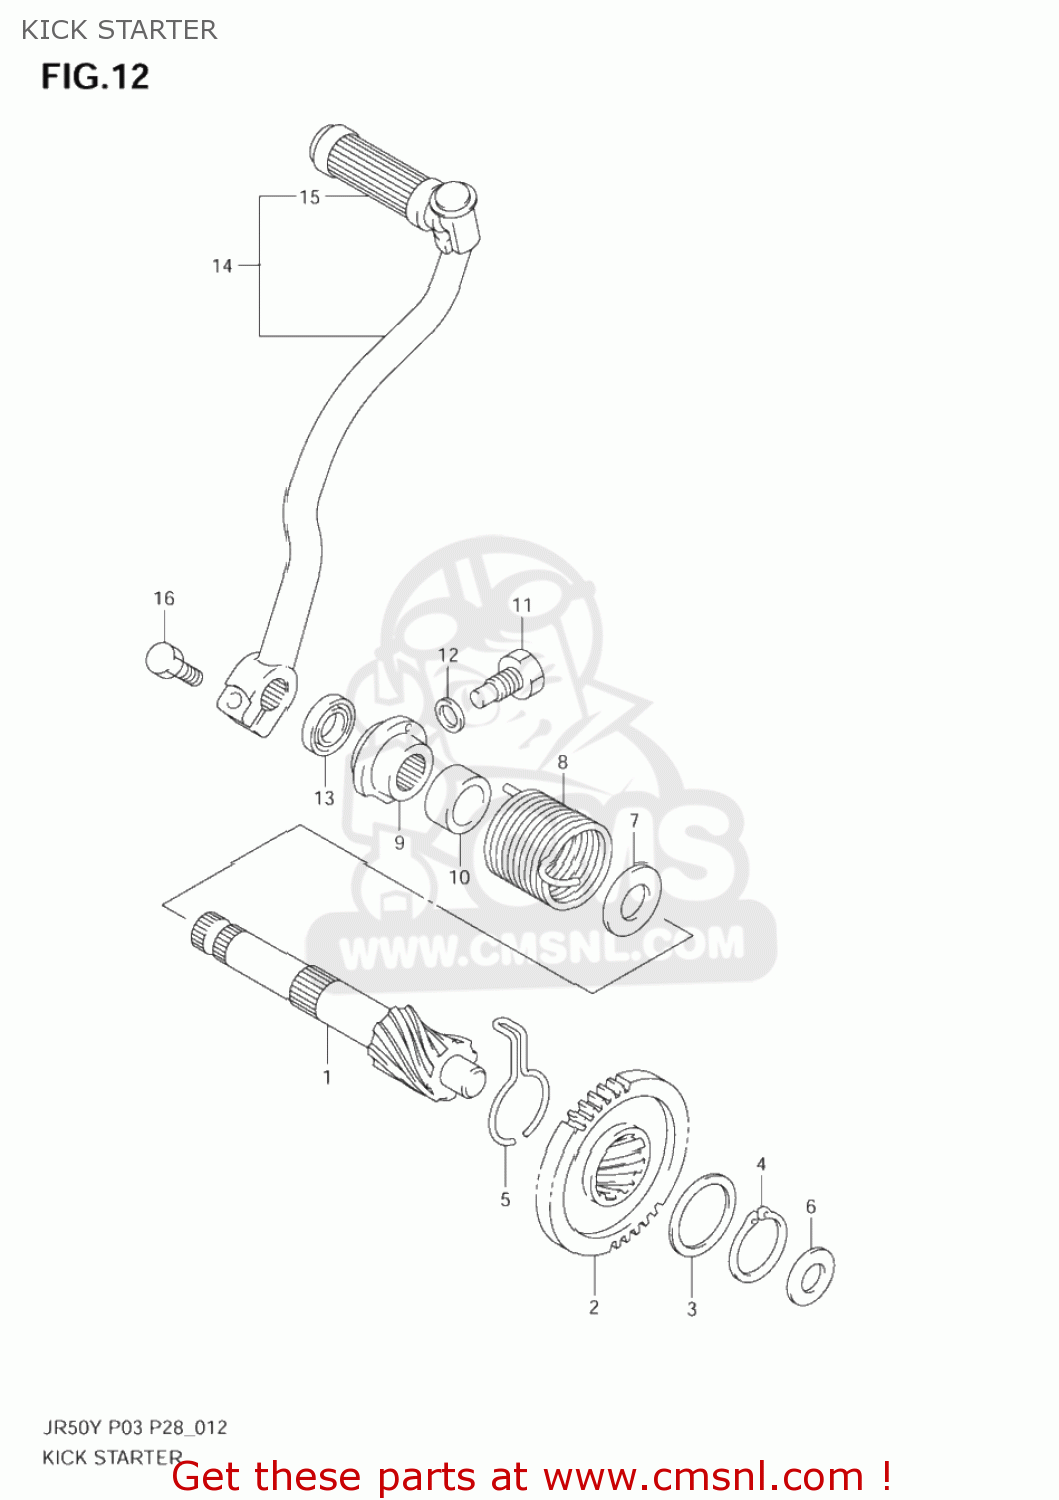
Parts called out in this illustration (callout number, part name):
1	SHAFT,KICK STARTER
2	GEAR,KICK STARTER DRIIVE
3	WASHER
4	CIRCLIP
5	RETAINER,SNAP
6	WASHER
7	WASHER(16X30X1)
8	SPRING
9	LIFTER,KICK STARTER
10	GUIDE,KICK RETURN SPRING
11	BOLT(10X17)
12	GASKET(10X14X3.6) (NAS)
13	SEAL,OIL(14X24X6)
14	LEVER ASSY,KICK STARTER
15	RUBBER,KICK STARTER PEDAL
16	BOLT
